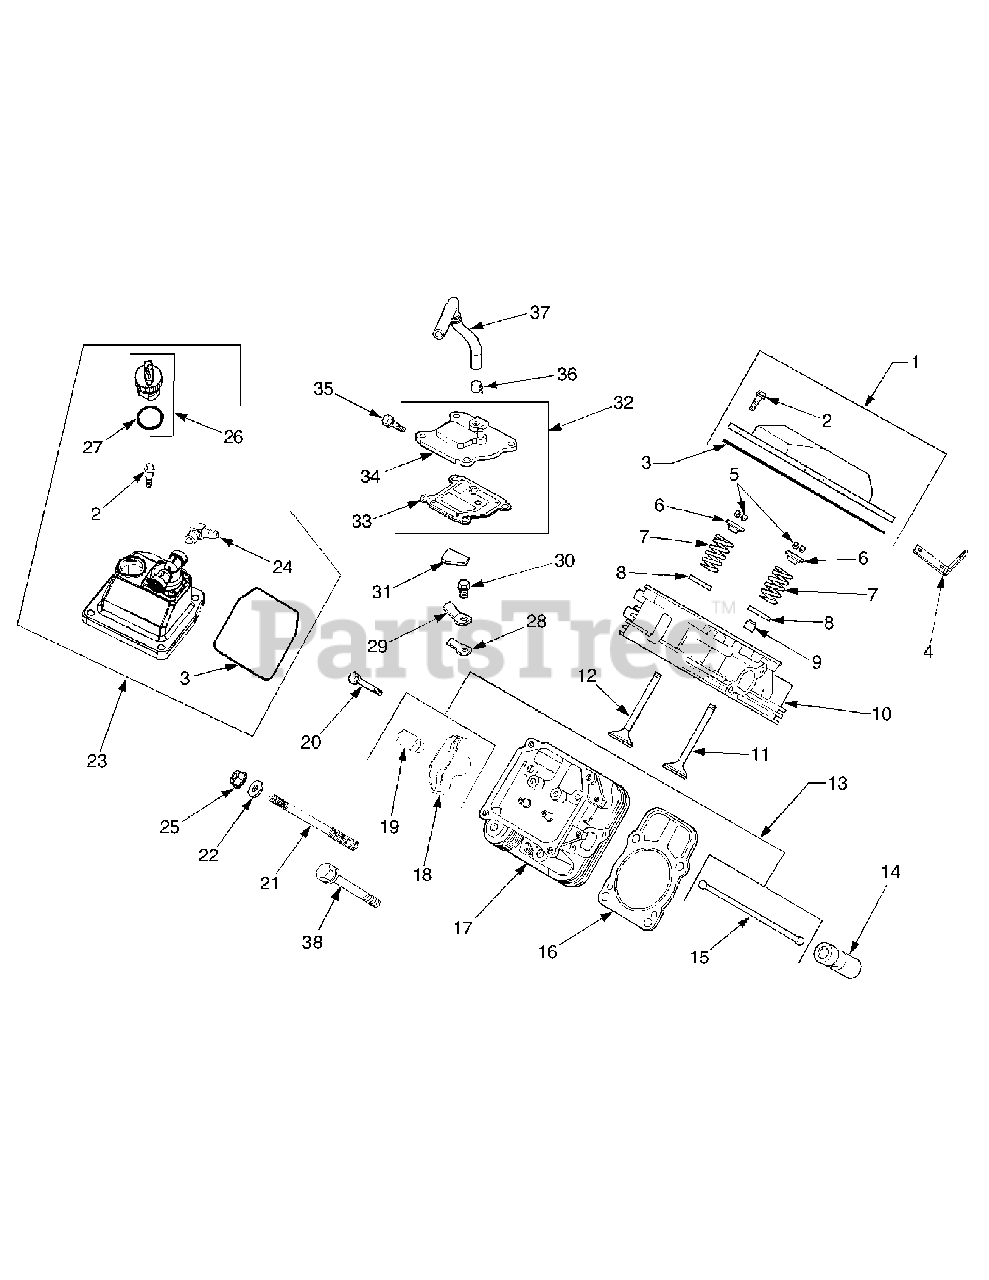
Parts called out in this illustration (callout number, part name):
1	Kit, Valve Cover
2	Screw, Hx. Flng, M6 x 1.0 x 30
3	O-Ring, Valve Cover
4	Strap, Lifting
5	Kit, Retainer
6	Cap, Valve Spring
7	Spring, Valve
8	Retainer, Spring
9	Seal, Valve Stem
10	Kit, Cylinder Head #1
11	Valve, Intake Std
11	Valve, Intake, .25mm
12	Valve, Exhaust Std
12	Valve, Exhaust, .25mm
13	Kit, Valve Train
14	Lifter, Valve
16	Kit, Cylinder Head Gasket
17	Kit, Cylinder Head #2
19	Pivot, Rocker Arm
20	Screw, Hex Flng, M6 x 1.0 x 34
21	Stud, Cylinder Head
22	Washer, Flat
23	Cover Kit, Fuel Pump Valve
24	Connector, 90°.
25	Nut, Hex Flange, M8 x 1.25
26	Cap Assembly, Oil Fill
27	O-Ring
28	Reed, Breather
29	Retainer, Breather Reed
30	Screw, Hex Flng, M5 x 0.8 x 10
31	Filter, Breather
32	Kit, Breather
33	Gasket, Breather
34	Cover, Breather
35	Screw, Hex Flng M6 x 1.0 x 20
36	Clamp, Breather
37	Hose, Breather
38	Screw, Hex Flange, M10 x 1.5 x 90
